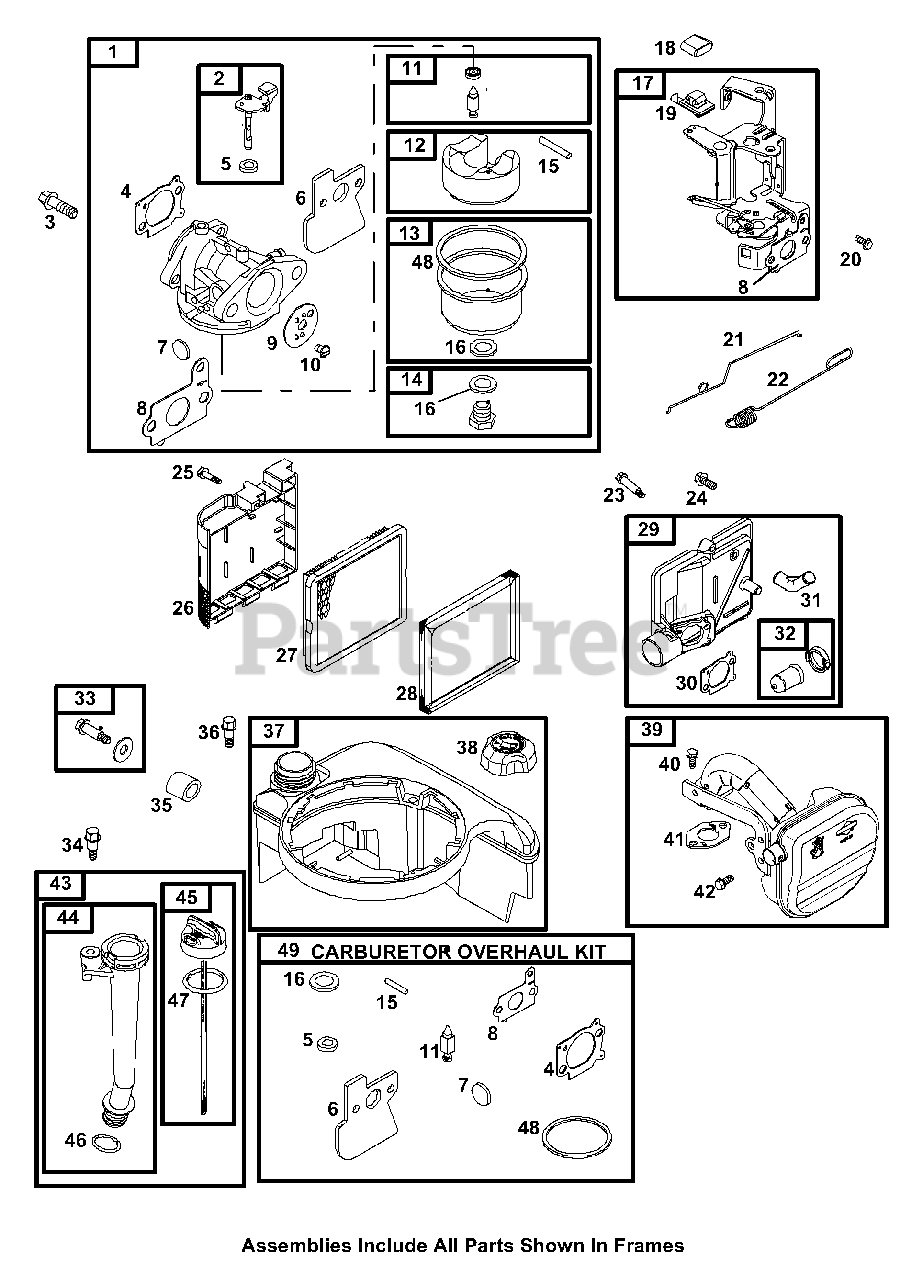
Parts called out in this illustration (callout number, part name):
1	Carburetor
2	Shaft-Throttle
3	Screw (Carburetor)
4	Gasket-Air Cleaner
5	Seal-Choke/Throttle Shaft
6	Spacer-Carburetor
7	Plug-Welch
8	Gasket-Intake
9	Valve-Throttle
10	Screw (Throttle Valve)
11	Kit-Needle/Seat
12	Float-Carburetor
13	Bowl-Float
15	Pin-Float Hinge
16	Washer-Sealing
17	Bracket-Control
18	Sleeve-Lever
19	Switch-Stop
21	Link-Mechanical Governor
22	Spring - Governor
23	Screw (Air Cleaner Base to Carb.)
24	Screw (Air Cleaner Primer Base)
25	Screw (Air Cleaner Cover)
26	Cover-Air Cleaner
27	Filter-A/C Cartridge
28	Filter-Pre Cleaner
29	Base-Air Cleaner Primer
30	Gasket-Air Cleaner
32	Primer-Carburetor
33	Kit-Screw/Washer
34	Screw (Dipstick Tube)
35	Spacer-Fuel Tank
36	Screw (Fuel Tank)
37	Tank-Fuel
38	Cap-Fuel Tank
40	Screw (Muffler)
41	Gasket-Exhaust
42	Screw (Muffler)
43	Order Component Part
44	Dipstick Tube
45	Dipstick
46	O-Ring Seal (Dipstick Tube)
47	O-Ring Seal (Dipstick)
48	Gasket-Float Bowl
49	Kit-Carburetor Overhaul
